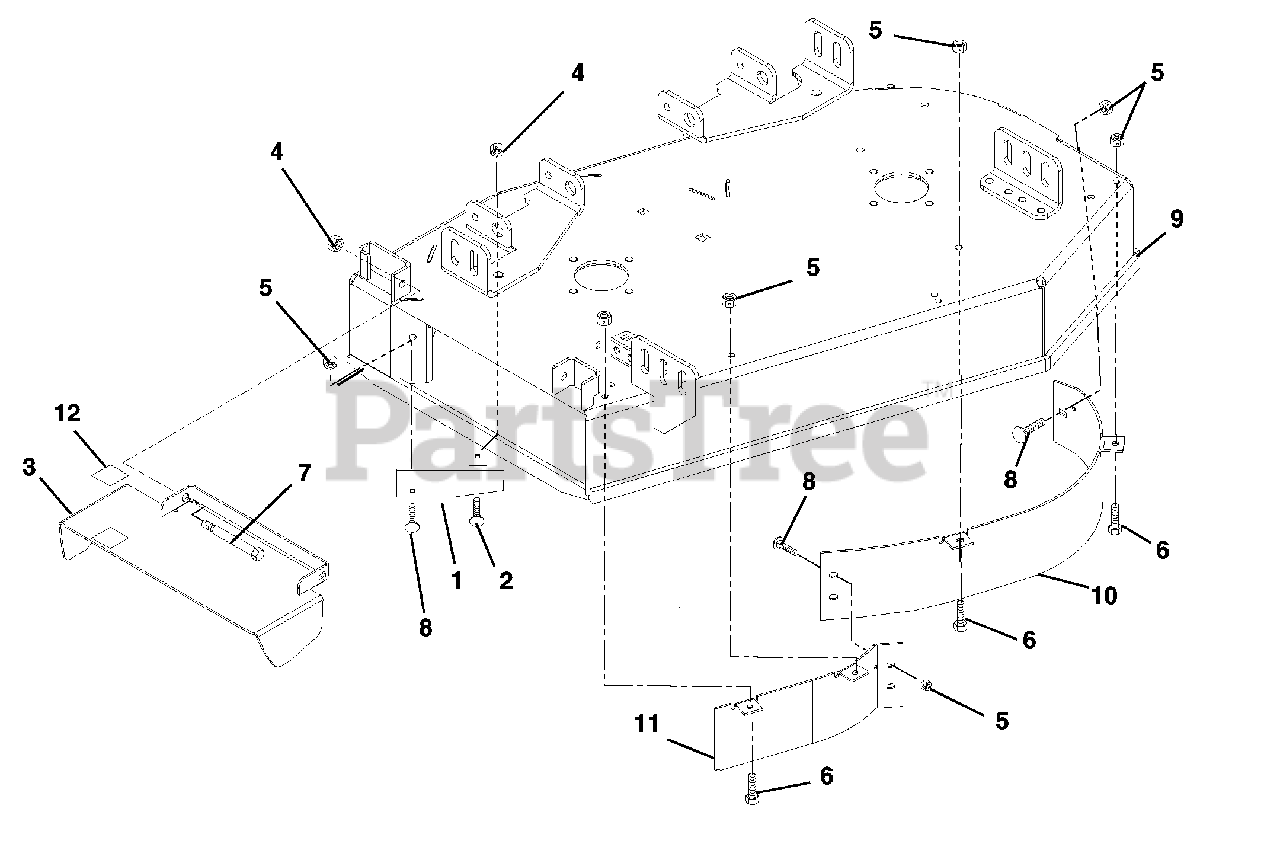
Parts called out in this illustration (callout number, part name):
1	Baffle, Deflector
2	Bolt-Round Head Square Neck .38-16 x 1.00 Grade 5
3	Chute-Discharge
4	Nut-Locking-Top-Flange .38-16
5	Nut-Locking-Top-Flange .31-18
6	Bolt-Hex .31-18 x .75 Grade 5
7	Bolt-Shoulder .38-16 x .50 Socket Head
8	Bolt-Round Head Square Neck .31-18 x .75 Grade 5
9	Weldment, 34" Deck
10	Baffle, 34" Front Left Hand
11	Baffle, 34" Front Right Hand
12	Grip, Pedal
